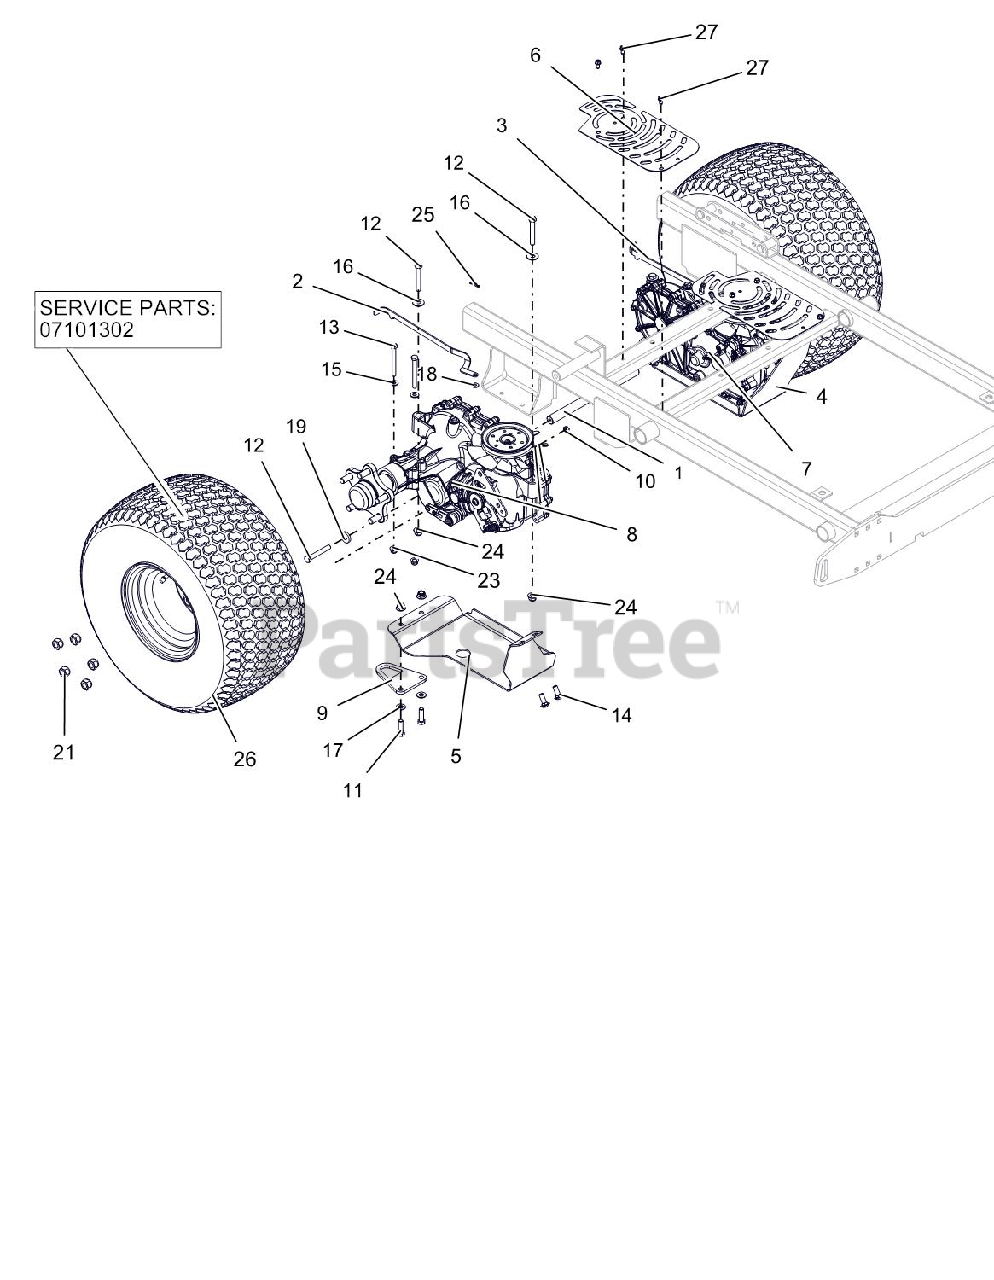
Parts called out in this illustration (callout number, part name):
1	SHAFT, CROSS BRACE
2	BRKT, LH DUMP VALVE
3	BRKT, RH DUMP VALVE
4	PLATE, LH SKID
5	PLATE, RH SKID
6	GUARD, PROSTANCE FAN
7	TRANSAXLE, ZT3400, LH
8	TRANSAXLE, ZT3400, RH
9	BRKT, TIE DOWN
10	@NUT-LK-CTR-JAM .31-18 YWZC
11	@BLT-HEX .38-16X1.25 GR5 YWZC
12	@BLT-HEX .38-16X2.50 GR5 YWZC
13	@BLT-HEX .31-18X3.00 GR5 YWZC
14	@BLT-RDHDSQNK .38-16X1.00 G5YZ
15	@WSHR-FL-STL.312X.734X.065 YWZ
16	@WSHR-FL-STL.438X1.00X.083 YWZ
17	@WSHR-FL-STL.406X.812X.065 YWZ
18	@WSHR-FL-STL.281X.62X.065 YWZC
19	WSHR-FL-STL .406X1.00X.188 YWZ
21	WHEEL NUT .500-20 YZ
23	@NUT-LK-NYL-FLG .31-18 YWZC
24	@NUT-LK-NYL-FLG .38-16 YWZC
25	PIN-HAIR, ENDRIES #25 YWZC
26	ASM, WHL/TIRE 20X10.5-8 RADIAL
26	TIRE, 20 X 10.5-8 4 PLY RADIAL
27	SCR-TAP .25-20X.50 HWH TR YWZ
